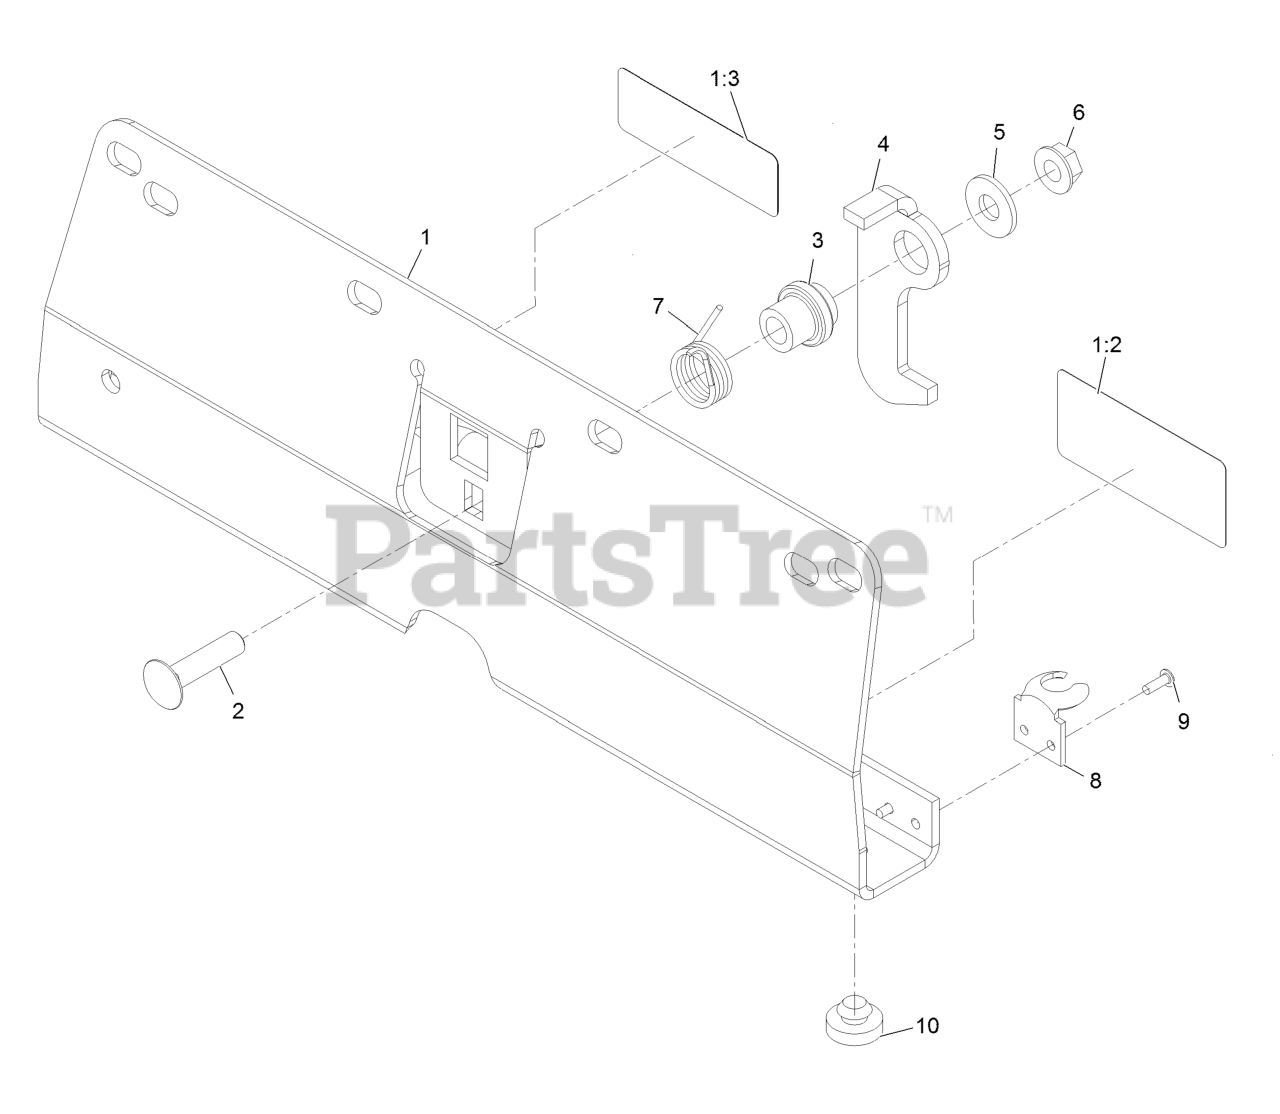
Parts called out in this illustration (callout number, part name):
1	ASM,LATCH PLATE S.O.
1:2	DECAL-ANTIFREEZE
1:3	DECAL-WARNING, PINCH POIN
2	SCREW-CARR
3	BUSHING-LATCH, SEAT
4	HOOK,LATCH
5	WASHER-FLAT
7	SPRING,LATCH
8	KEEPER
